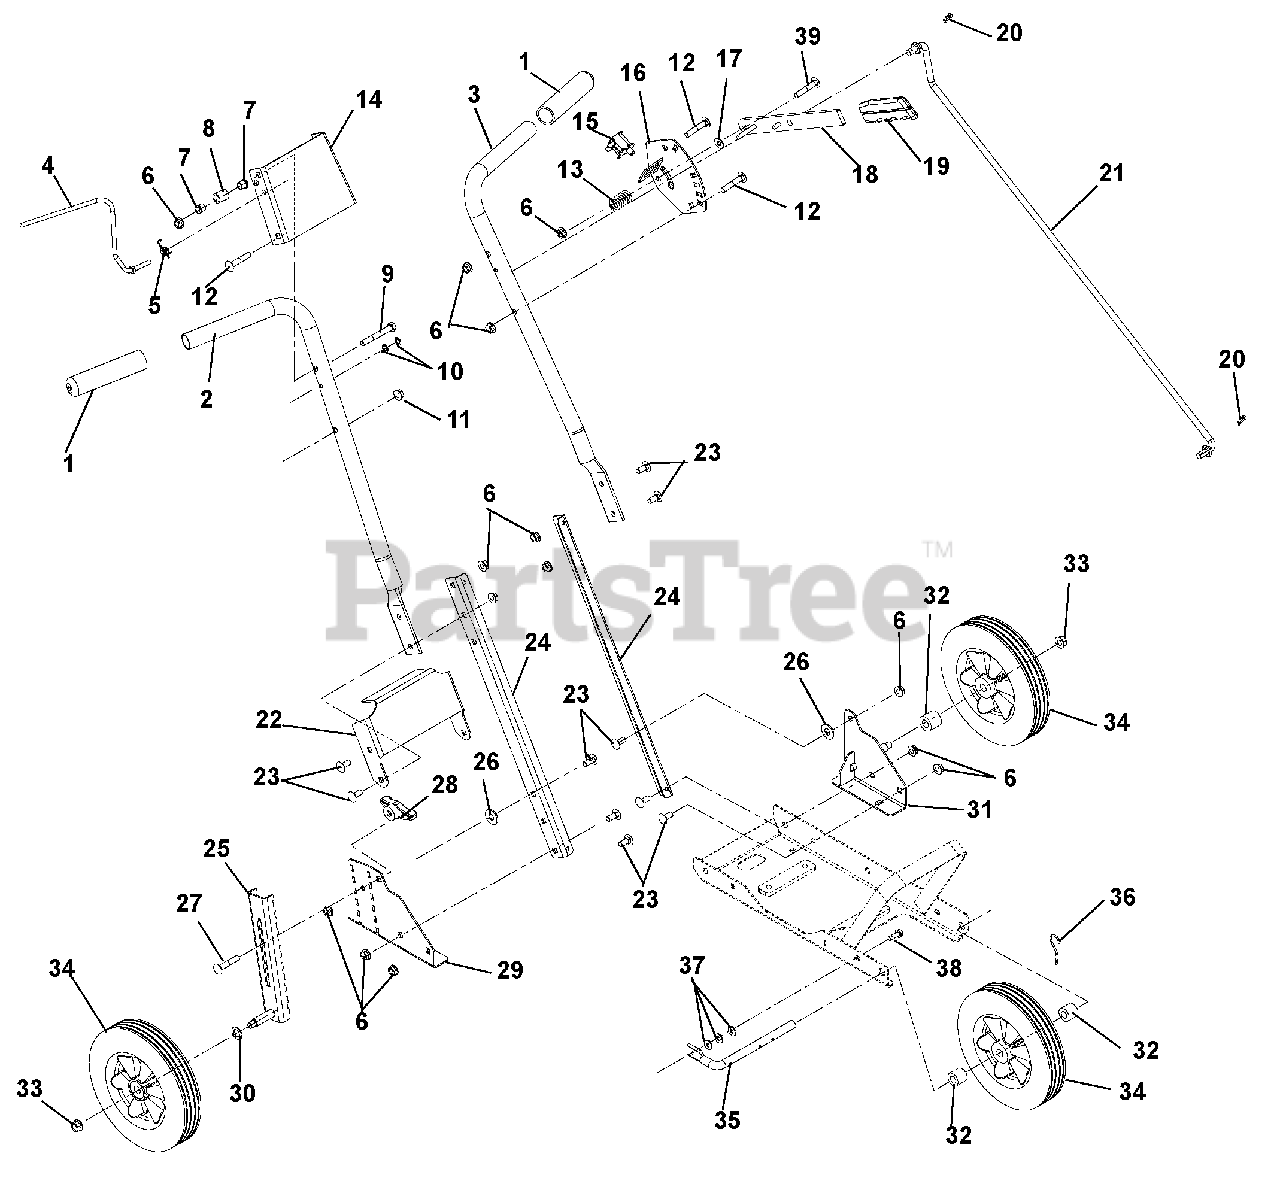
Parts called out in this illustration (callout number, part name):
1	Handle Grip
2	Handlebar, Upper RH
3	Handlebar, Upper LH
4	Rod, OPC
5	Spring, Torsion
6	Nut, Locking Top Flange .31-18
7	Bushing, Flange .325 x .444 x .440 x .560
8	Spacer, Ground
9	Bolt, Hex .31-18 x 2.50 Grade 5
10	Ring, Retaining Ext. .250 x .010
11	Nut, Locking Top Flange .31-18
12	Bolt, Round Head Square Neck .31-18 x 1.75 Grade 5
13	Spring, Compression .125 x .781 x 1.250
14	Panel, Upper
15	Switch, Snap
16	Detent, Pivot
17	Washer, Flat Steel .344 x .688 x .065
18	Lever, Pivot
19	Grip, Parking Brake
20	Pin, Hair #25
21	Rod, Pivot
22	Panel, Lower
23	Bolt, Round Head Square Neck .31-18 x .75 Grade 5
25	Leg Drop, Wheel
26	Washer, Flat Steel .438 x 1.00 x .083
27	Bolt, Round Head Square Neck .31-18 x 1.75 Grade 5
28	Knob, Clamping .312-18
29	Bracket, RH Wheel Support (986102)
30	Washer, Flat Steel .52 x .827 x .062
31	Bracket, LH Wheel Support
32	Spacer, Wheel
33	Nut, Locking Top Flange .38-16
34	Wheel, 8.0 x 1.75 x .50
35	Axle, Front
36	Hairpin, #7 Clip .094 x 2.31
37	Washer, Flat Steel .281 x .62 x .065
38	Screw, Tapping .25-20 x .75
39	Bolt, Round Head Square Neck .31-18 x 2.25
